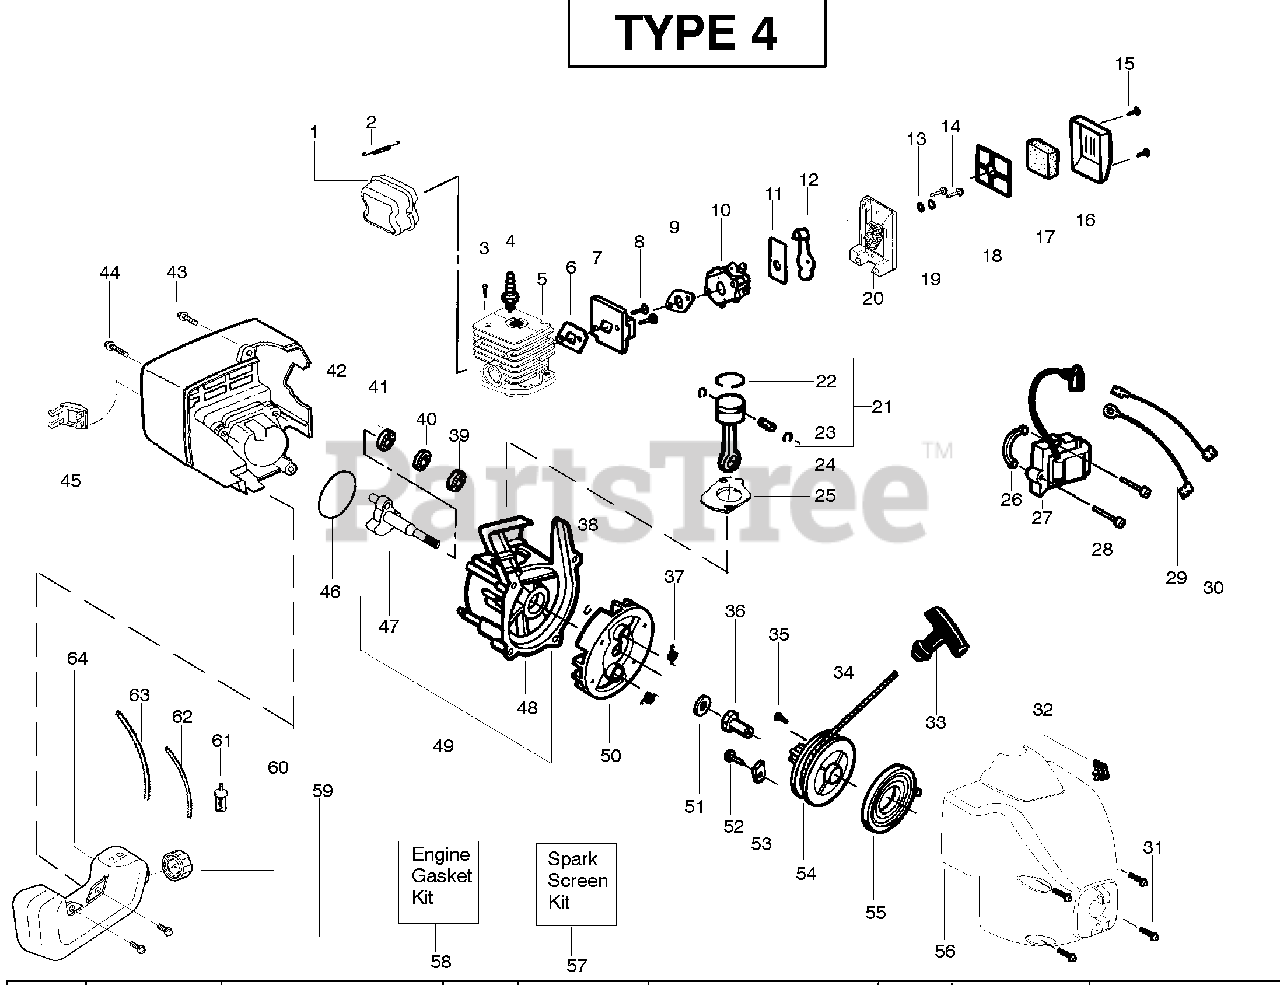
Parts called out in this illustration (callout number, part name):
1	Kit - Muffler
2	Muffler Spring
3	Screw-Cylinder
4	Spark Plug (RCJ 6Y)
5	Kit - Cylinder
6	Gasket-Cyl/Carb.(kit)
7	Adaptor-carb.
9	Gasket-Carb.(kit)
10	Kit-Carb. (WA-226)
10	Kit-Carb. (WT-631)
11	Plate-Choke Mounting
12	Lever-Choke
16	Cover-Air Box
17	Foam-Air Filter
18	Plate-Air Filter Support
19	Spacer-Choke
21	Kit - Piston
22	Piston Ring
23	Retainer-Piston Pin
24	Assy-Connecting Rod
25	Gasket-Cylinder(kit)
26	Spacer-Module
27	Ignition Module
29	Assy-Ground Wire
30	Assy-Leadwire
31	Screw
32	Kit-Switch
33	Handle-Starter
34	Kit - Rope
36	Coupling-Drive
37	Spring-Starter Dog
38	Retain. Ring-C'shaft
39	Bearing-Outer
40	Kit-Seal C'case
41	Bearing-Inner
44	Screw
45	Guard-Muffler
46	O-Ring-C'case(kit)
47	Assy-Crankshaft
48	Assy-Crankcase
49	Assy-C'case & C'shaft
50	Assy-Flywheel
51	Washer-Flat
53	Retainer-Can
54	Kit-Starter Pulley
55	Spring-Starter
56	Assy-Fan Housing
57	Kit-Spark Screen
58	Kit-Engine Gasket
59	Retainer-Tank
60	Assy-Fuel Cap
61	Assy-Fuel Pickup
62	Kit-Fuel Line
63	Kit-Fuel Line
64	Assy-Fuel Tank
